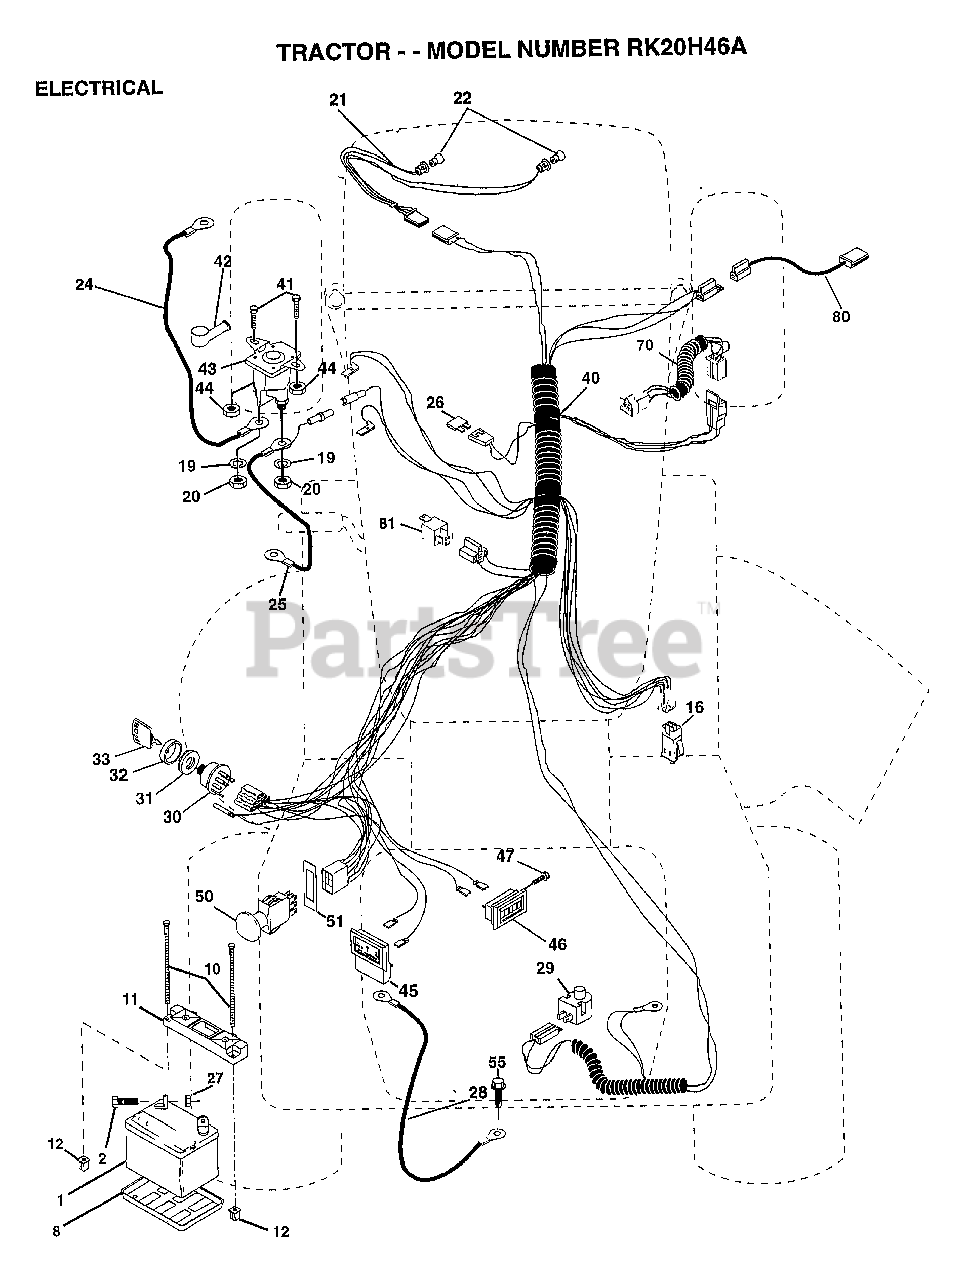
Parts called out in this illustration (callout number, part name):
2	BOLT LT
8	"TRAY T, BATTERY"
11	HOLDDOWN BATTERY
16	SWITCH INTERLOCK
20	NUT
21	HARNESS.ASM.LIGHT W/4152J
22	HEADLAMP BULB
24	"CABLE T, BATTERY"
25	CABLE.6GA.22W/16W
26	FUSE.15 AMP
27	NUT
28	CABLE.GRND.6GA.21
29	SWITCH.PLUNGER
30	SWITCH IGN 4POS
31	NUT IGNITION
32	COVER KEY SWITCH
33	KEY
40	HARNESS.IGNITION
41	BOLT HXHD FIN
44	NUT HXKEP 1/4X20
45	AMMETER
46	HOUR METER T
47	SCREW
50	PTO SWITCH.BLK
51	RING RETAIN PTO
55	SCREW LT
70	HARNESS.ENGINE.KOHL
80	HARNESS.CLUT.EVX.
81	RELAY ASSY T
